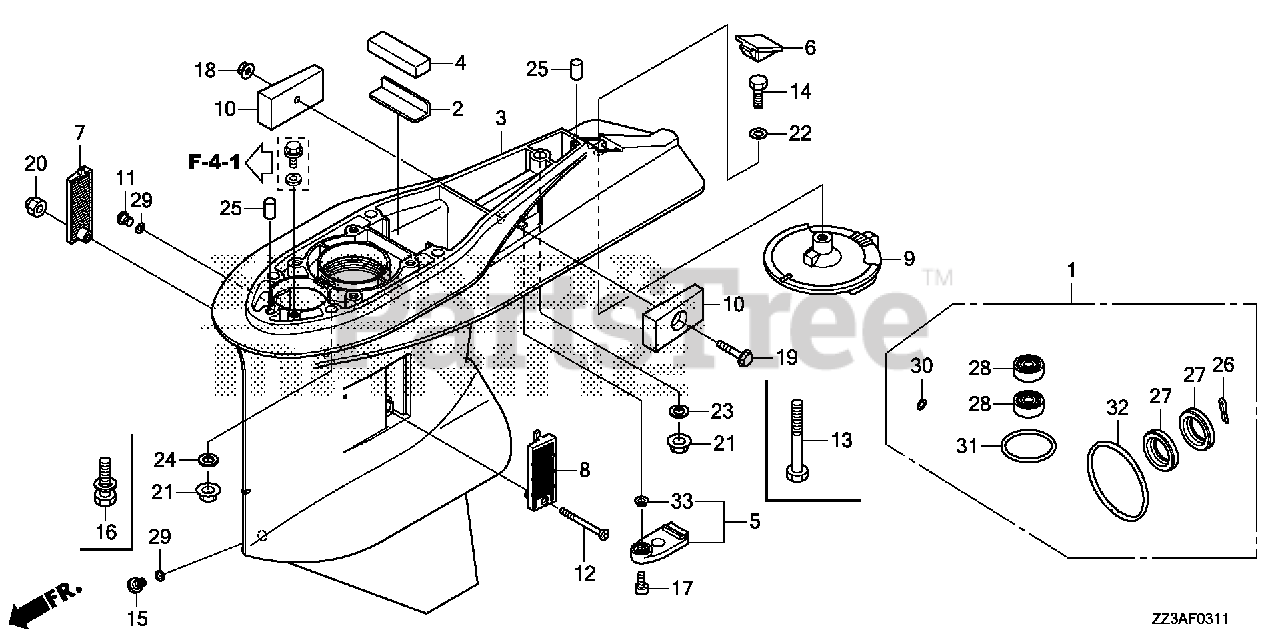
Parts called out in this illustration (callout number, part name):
1	CASE KIT, GEAR (P/T)
2	PLATE, RUBBER SETTING
3	CASE, GEAR *NHB14M* (AQUA MARINE SILVER METALLIC)
4	GROMMET, GEAR CASE
5	COVER B, GEAR CASE
6	GROMMET, GEAR CASE
7	SCREEN, R. WATER
8	SCREEN, L. WATER
9	TAB, TRIM *NHB14M* (AQUA MARINE SILVER METALLIC)
10	METAL, ANODE
11	BOLT, OIL CHECK
12	SCREW, FLAT (5X55)
13	BOLT, HEX. (10X80)
14	BOLT, HEX. (8X25)
15	BOLT, DRAIN PLUG
16	BOLT-WASHER (10X40)
17	BOLT, SOCKET (6X16)
18	NUT, SELF-LOCK (6MM)
19	BOLT, FLANGE (6X35)
20	NUT, SELF-LOCK (5MM)
22	WASHER, PLAIN (8MM)
23	WASHER, PLAIN (10MM)
25	PIN, DOWEL (6X10)
26	PIN, SPLIT (4.0)
27	SEAL, WATER (30X45X7)
28	SEAL, WATER (12X21X6)
29	O-RING (6.9X1.45)
30	O-RING (6.9X1.45)
31	O-RING
32	O-RING (94X4.1)
33	COLLAR, DISTANCE (6.5X9X3)
